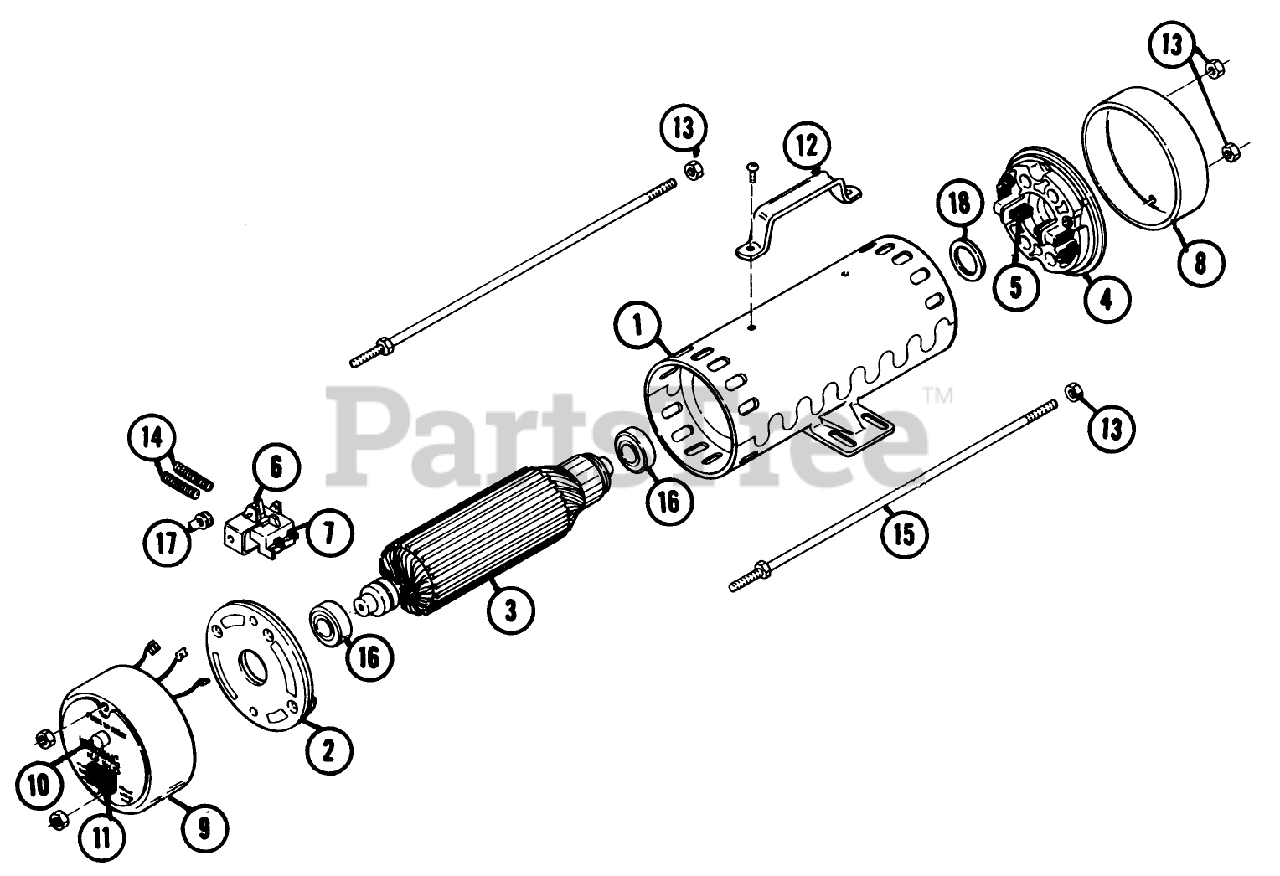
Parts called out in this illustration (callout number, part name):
1	Shell Magnet Assembly
2	Front End Bell Assembly w/o Brush Holder
3	Armature Assembly w/Brushes
4	Rear End Bell Assembly w/Brushes
5	Brush Assembly (D.C.)
6	Brush Holder (A.C.)
7	Brush Assembly (A.C.)
8	Cover (D.C. Side)
9	Bearing
11	Threaded Rod
12	Handle
14	Spring
15	Threaded Rod
16	Bearing
17	Screw
18	Washer
